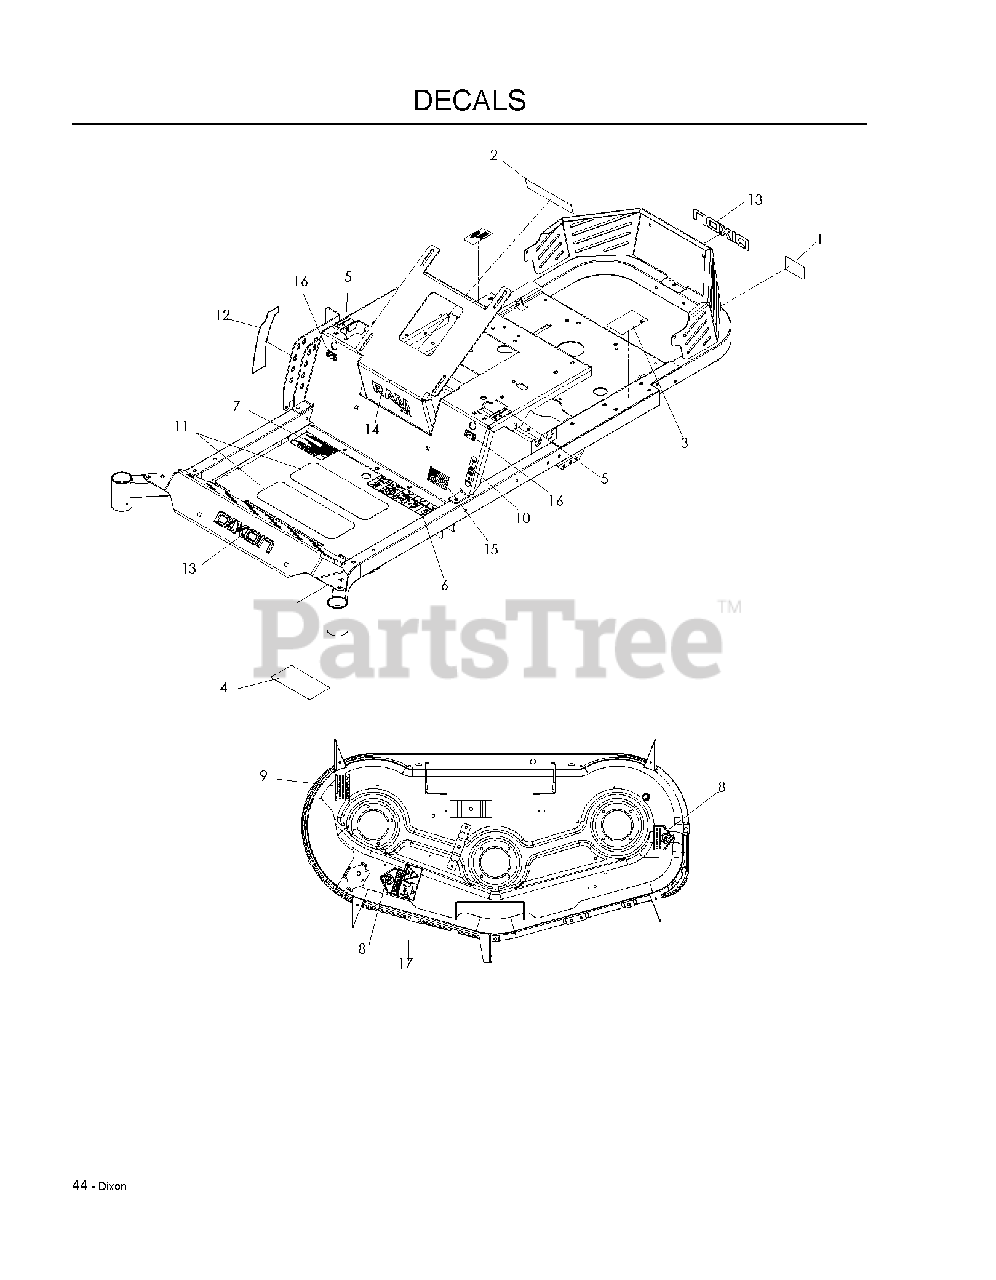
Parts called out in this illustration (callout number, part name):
1	DECAL, PROP. 65
2	DECAL, BATTERY
3	DECAL, DO NOT MOUNT
4	DECAL, SERVICE
5	DECAL, MOTION CONTROL
6	DECAL, SAFETY WARNING
7	DECAL, WARNING
8	DECAL, CPSC
9	DECAL, CAUTION
10	DECAL, PARK BRAKE
11	ANTI-SKID PAD
12	DECAL, HEIGHT
13	DECAL, DIXON LOGO, DOMED
14	DECAL, RAM ZTR, 2008
15	DECAL, FLAG
16	DECAL, F.S.T.
17	DECAL, EURO SEVERING
